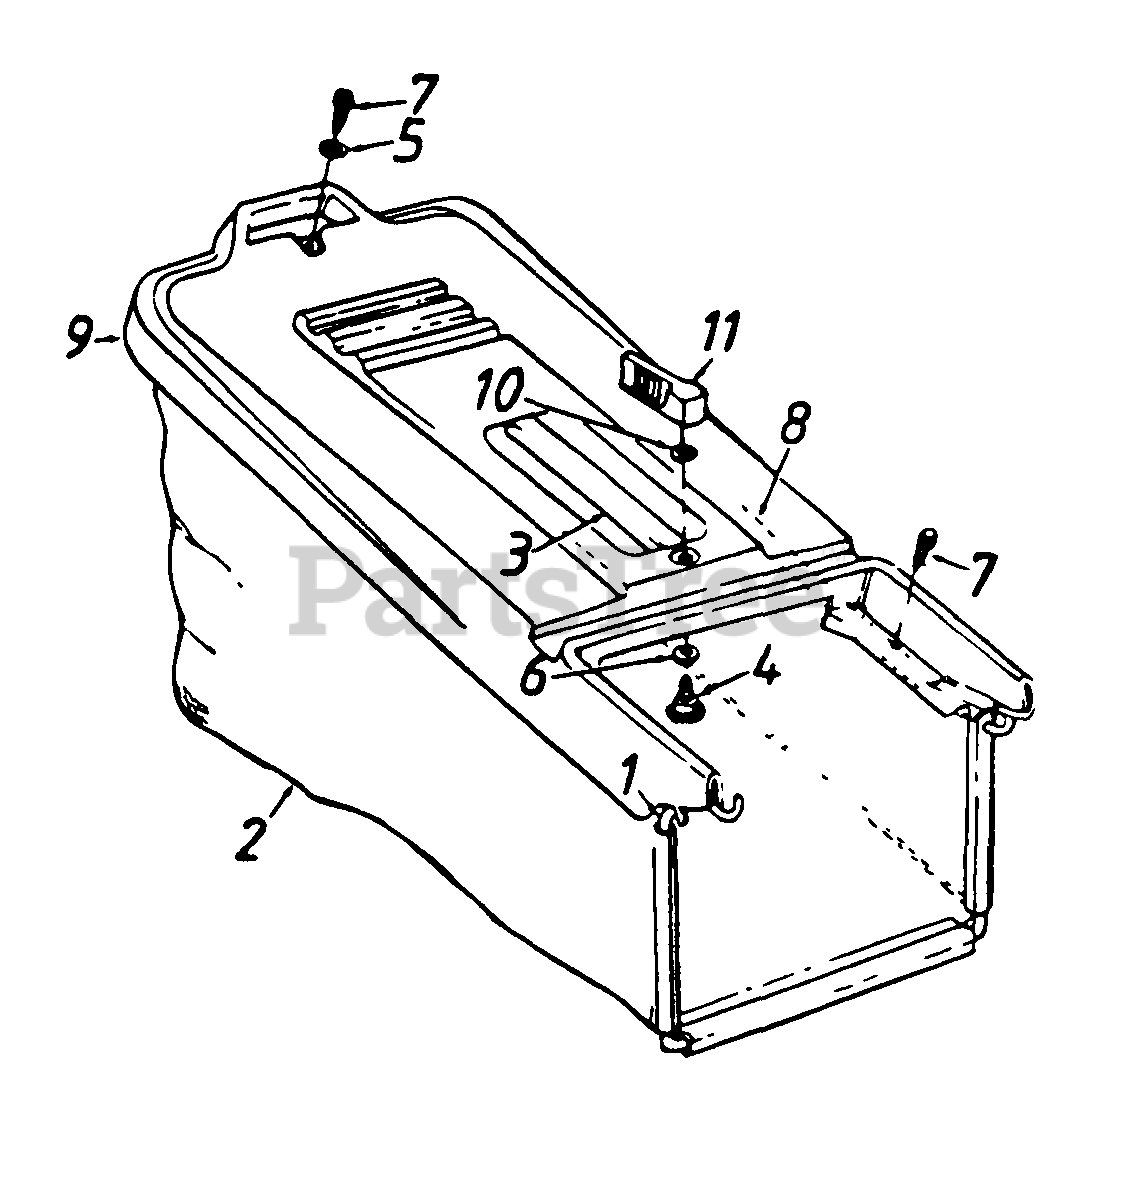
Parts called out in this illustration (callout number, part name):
2	Grass Bag
3	Hardtop Handle
4	Shoulder Bolt
5	Fl-Wash. .281" I.D.
6	Bowed Washer
7	Hex L-Wash. AB-Tap Scr. 1/4 x .62"
10	Internal L-Wash. 1/4" I.D.
11	Locking Knob
